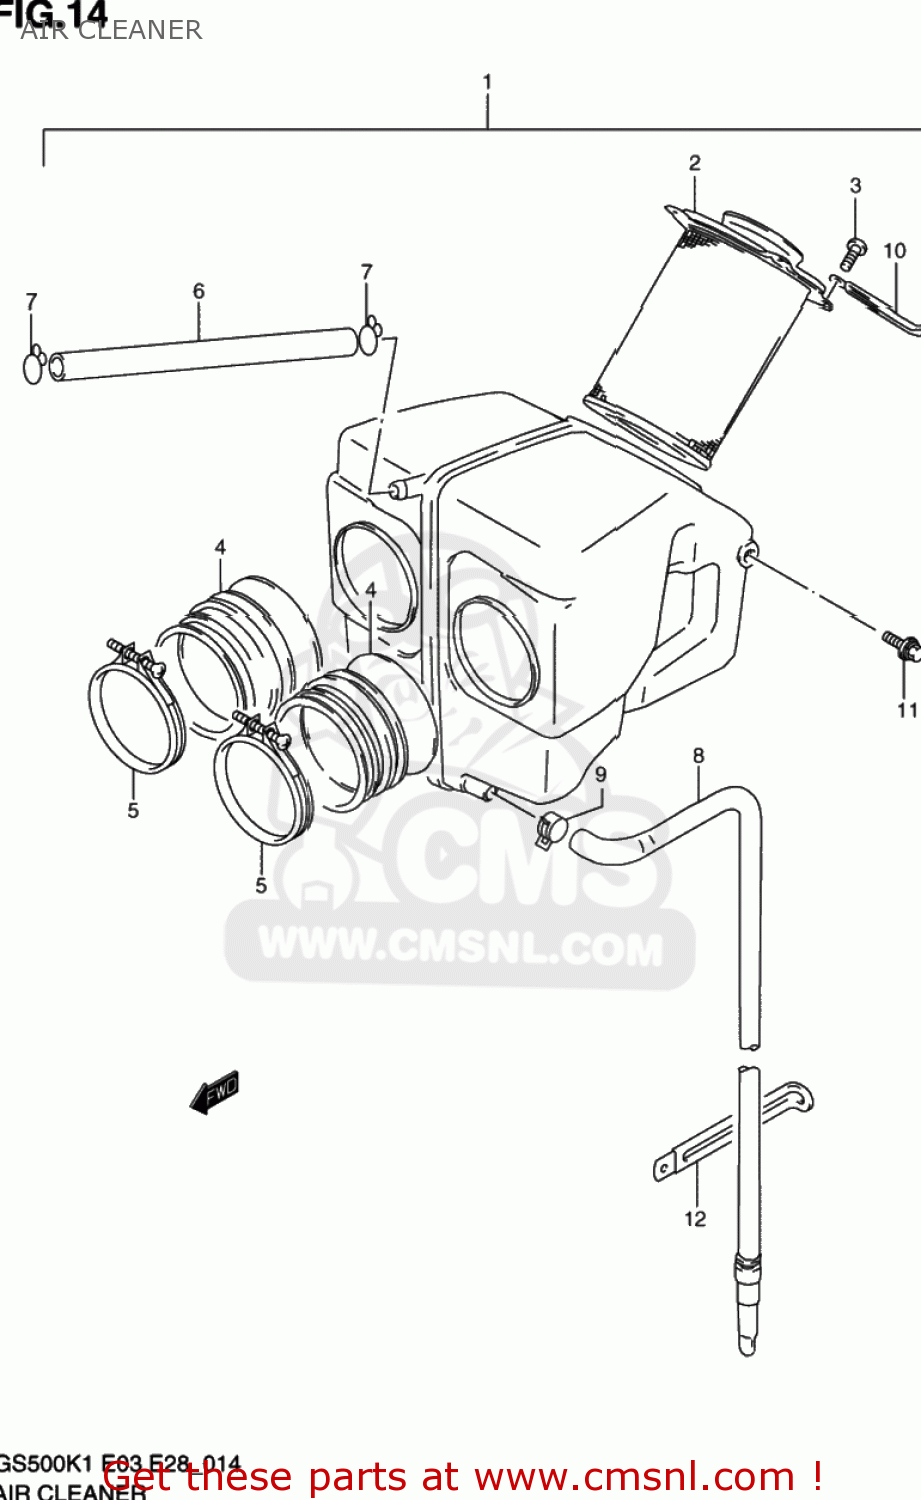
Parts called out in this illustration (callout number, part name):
1	CLEANER ASSY, AIR
2	FILTER ASSY
3	SCREW
4	TUBE,OUTLET
5	CLAMP
6	HOSE(11X15X600)
7	CLIP
8	TUBE,DRAIN
9	CLIP
10	CLAMP
11	BOLT
12	CLAMP(L:80 T:1.0)
